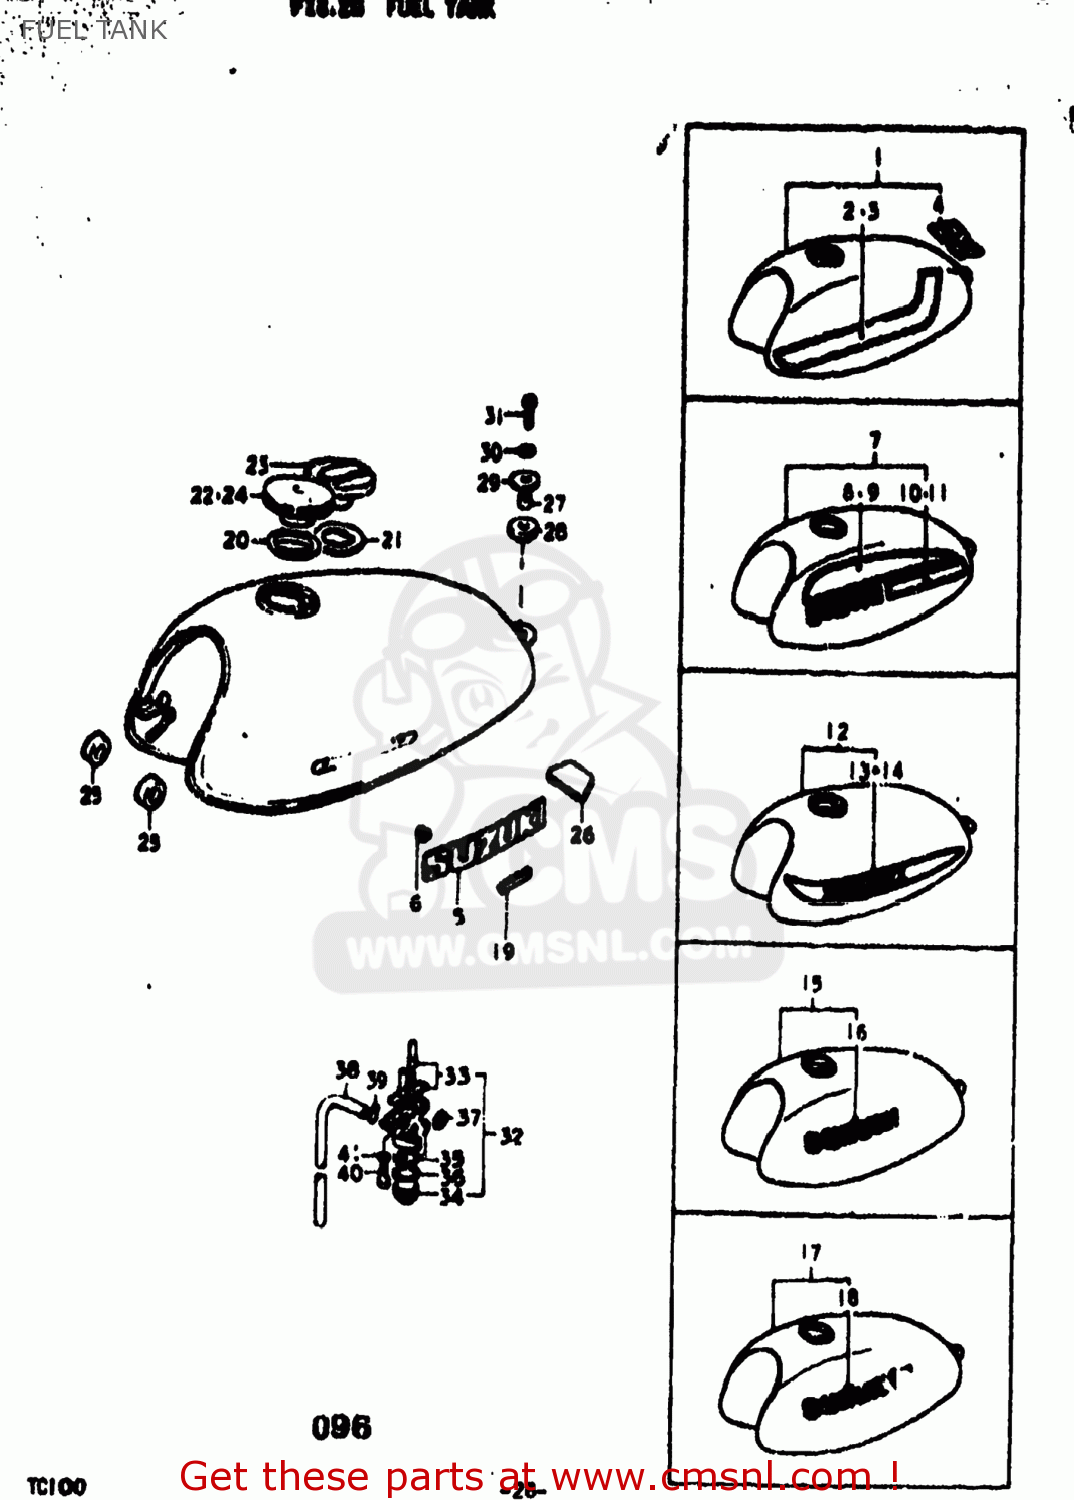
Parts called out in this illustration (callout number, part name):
1	TANK, FUEL K
2	TAPE,FUEL TANK
3	TAPE,FUEL TANK
5	EMBLEM
6	NUT
7	TANK ASSEMBLY,FUEL
8	TAPE,FUEL TANK
9	TAPE,FUEL TANK
10	EMBLEM
11	EMBLEM,FUEL TANK
12	TANK ASSEMBLY,FUEL
13	TAPE,FUEL TANK
14	TAPE,FUEL TANK
15	TANK ASSEMBLY,FUEL
16	EMBLEM
17	TANK ASSEMBLY,FUEL
18	EMBLEM
20	GASKET,FUEL TANK CAP (NAS)
21	GASKET (NAS)
22	CAP SET,FUEL TANK
23	CAP SET,FUEL TANK
24	CAP,FUEL TANK
25	CUSHION
26	CUSHION
27	SPACER(8.4X12X12)
28	CUSHION
29	WASHER
30	LOCK WASHER K,L,M,A
31	BOLT
32	COCK ASSEMBLY,FUEL
33	FILTER SET,FUEL COCK
34	CUP,FUEL COCK STRAINER
35	NET,STRAINER
36	GASKET,FILTER (NAS)
37	GASKET,LEVER (NAS)
38	HOSE
39	CLIP
40	SCREW
41	GASKET
